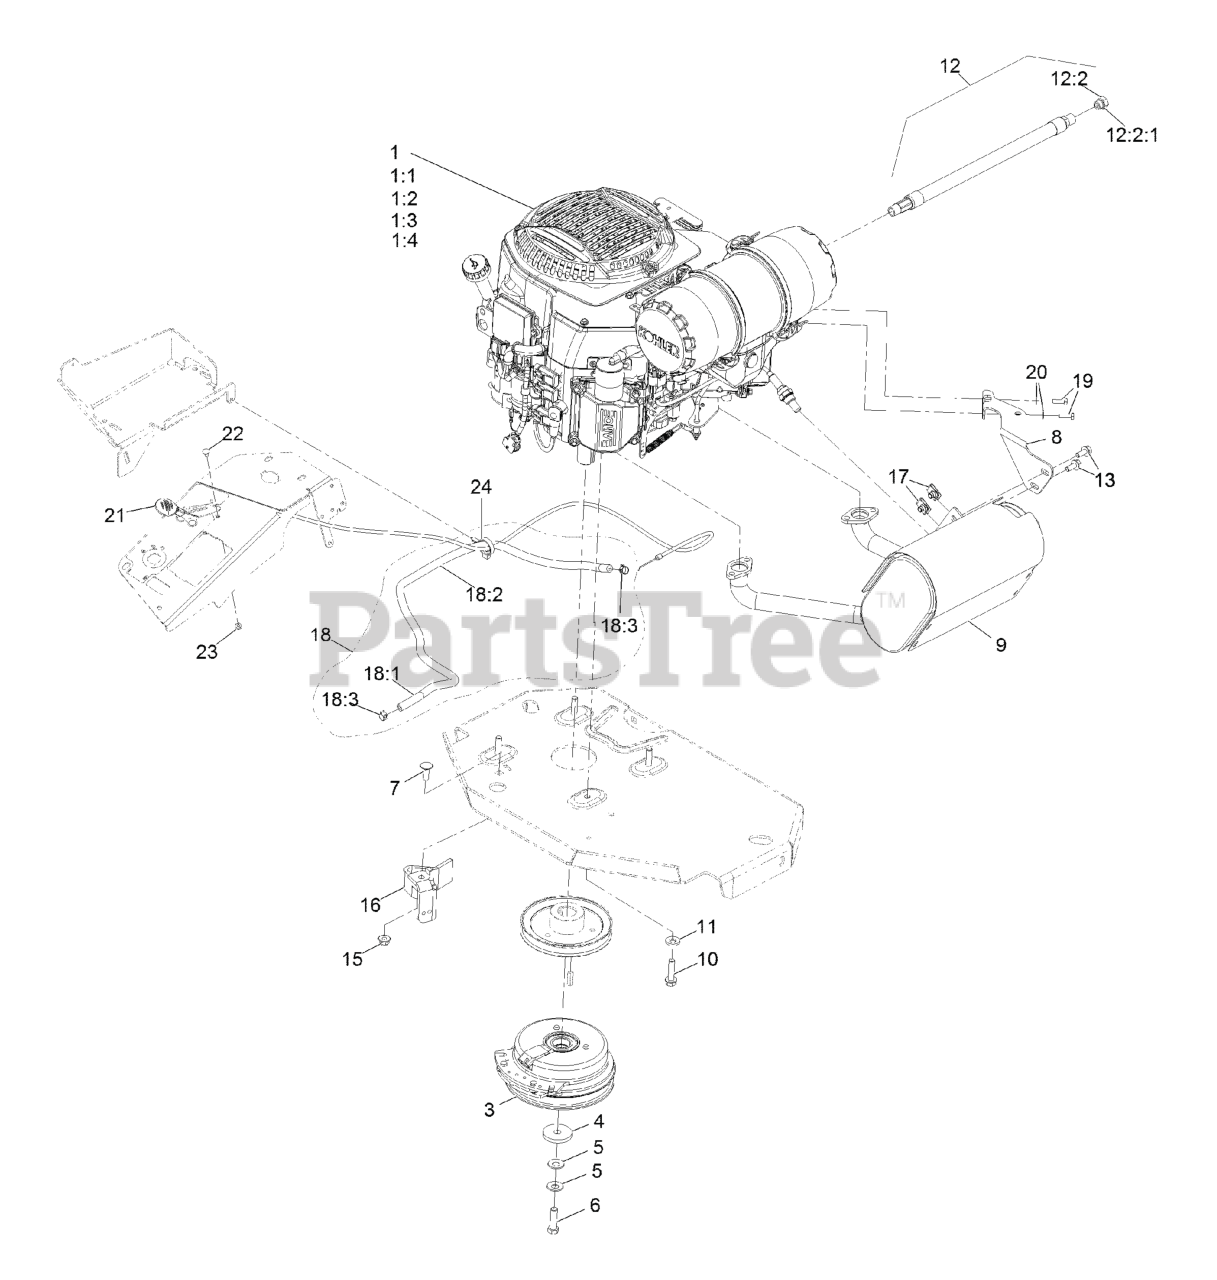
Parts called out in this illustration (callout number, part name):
1:1	Kohler 52 050 02-S Engine Oil Filter
1:2	Kohler 25 083 01-S Engine Air Filter
1:3	Kohler 25 083 04-S Safety Filter
1:4	Kohler 25 050 42-S Fuel Filter
3	CLUTCH KIT
4	WASHER-CLUTCH
5	WASHER-SPRING
6	SCREW-HH 7/16-20 X 1 1/2 W/LOCTITE
7	SCREW-CARR
8	MUFFLER BRACKET KIT
9	MUFFLER KIT
10	SCREW-HWH
11	WASHER-BELLEVILLE
12	OIL DRAIN HOSE ASM
12:2	PLUG-HH
12:2:1	O-RING
13	SCREW-HHF
15	NUT-HF, NI
16	CLUTCH-ANCHOR
18	FUEL LINE ASM
18:1	HOSE-FUEL
18:2	SLEEVE-THERMAL
18:3	CLAMP-HOSE
19	SCREW-HH M6-1 X 20Mm W/Patch
20	WASHER-SPRING
21	ASM,THROTTLE CABLE
22	BOLT-CARR
23	NUT-LOCK, NI
24	CLAMP-HOSE
